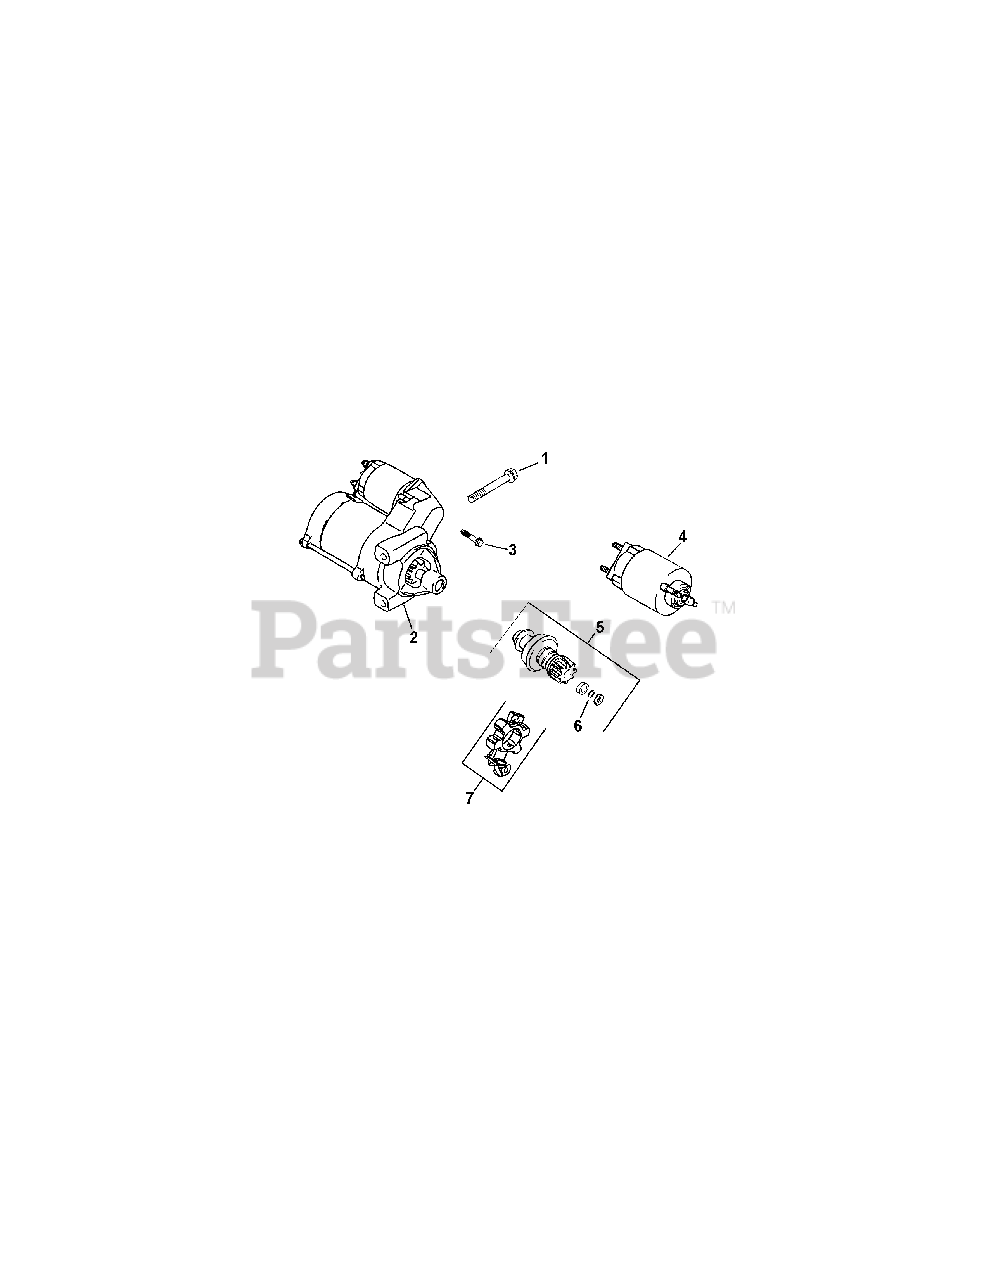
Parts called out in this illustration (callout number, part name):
1	Screw, hex flange M8x1.25x80 (2)
2	Starter, solenoid ass’y (Incl 3-7)
3	Screw, external torx hd. (3)
4	Kit, solenoid (Includes 3)
5	Kit, starter pinion (Includes 6)
7	Brush, holder
